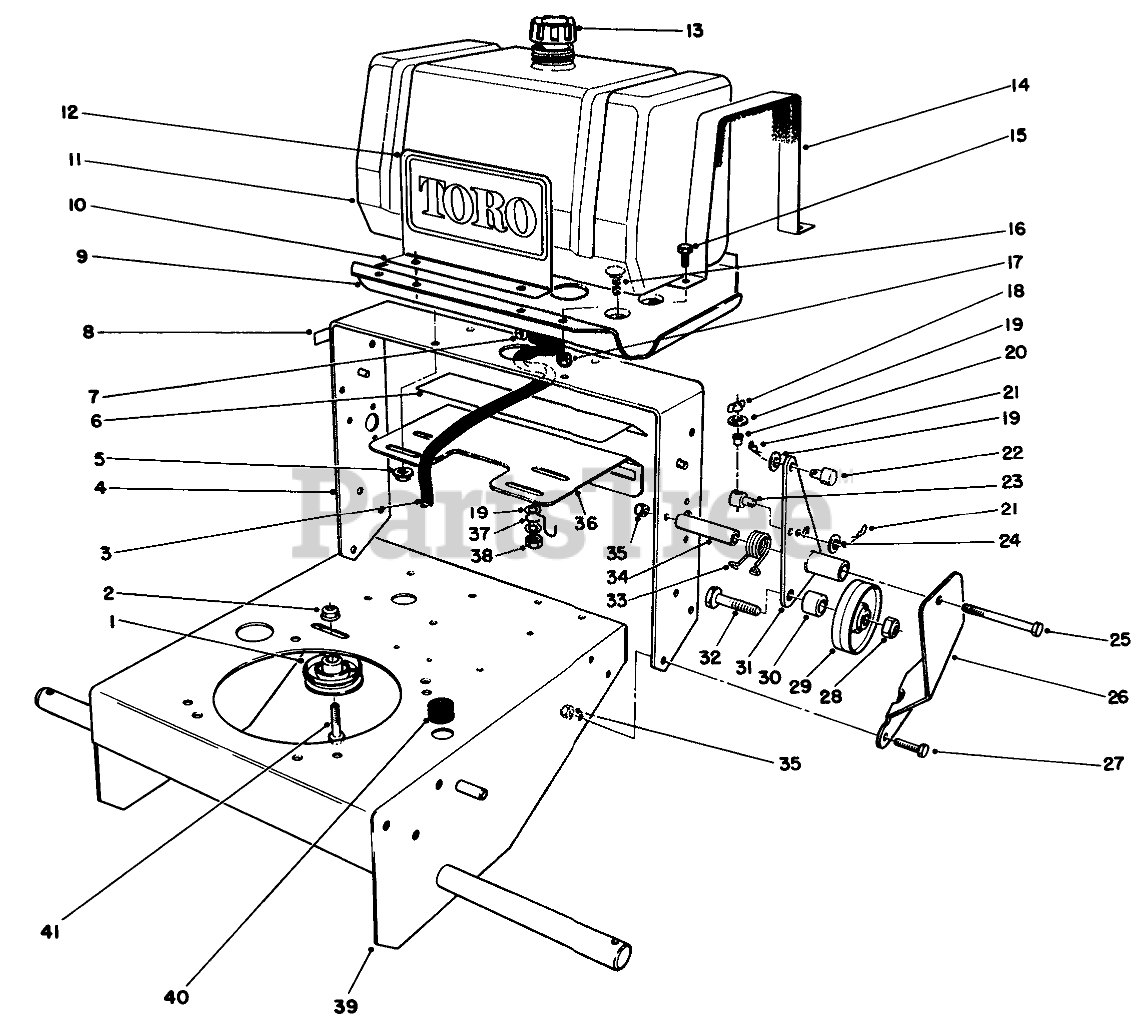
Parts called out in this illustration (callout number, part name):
1	PULLEY-IDLER
2	NUT-HF
3	HOSE-FUEL
4	Frame-Rear
5	NUT-HF
6	Decal-Ground Speed
7	CLAMP-WORM
8	Decal-Fuel Shut Off
9	PLATE-FUEL TANK
10	DECAL-PLATE
11	TANK-FUEL
12	DECAL
13	GAS CAP ASM
14	STRAP ASM
15	SCREW-HH
16	SCREW-CARR
17	NUT-LOCK, NI
18	NUT-WING
19	WASHER-PLAIN
20	BUSHING-NYLON
21	PIN-COTTER
22	ROD FITTING
23	FITTING-ROD
24	WASHER-PLAIN
25	SCREW-HH
26	Bracket-LH
27	SCREW-HH
28	NUT-LOCK, NI
29	IdlerWheel
30	WHEEL IDLER SPACER
31	Bracket-Idler, LH
32	SCREW-LEVELER
33	SPRING-TORSION, LH
34	PIVOT-IDLER SPACER
35	NUT-LOCK, NI
36	Plate
37	GAS LINE CLIP
38	NUT-LOCK, NI
39	Frame
40	GROMMET
41	SCREW-HH
